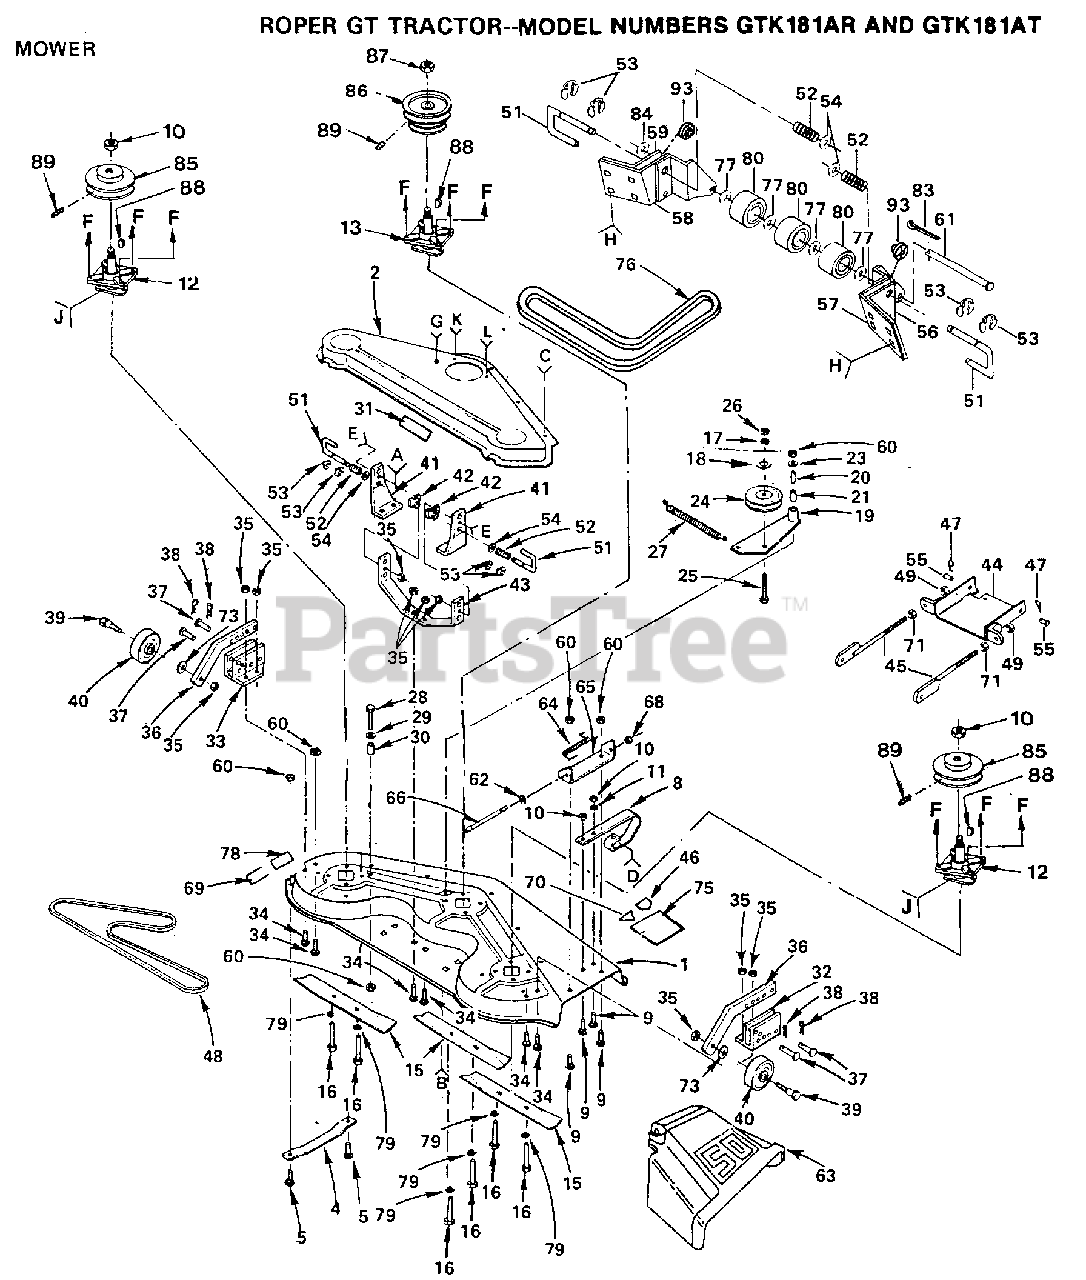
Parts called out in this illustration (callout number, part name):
2	COVER DECK T
4	RUNNER-LH M
5	BOLT
9	BOLT
11	WASHER
16	BOLT.7/16-14X3/4
17	LOCKWASHER
18	WASHER
19	ARM ASSY GT
23	WASHER
24	IDLER-FLAT T
26	NUT.HEX.3/8-16UNC
27	SPRING T
28	BOLT
29	WASHER M
30	SPACER SPLIT LT
32	GUAGE WHL BRKT GT
33	GUAGE WHL BRKT GT
34	BOLT
36	GUAGE WHL BAR GT
39	BOLT M
40	WHEEL.GAGE.BLK.PL
41	SUSP BRKT GT
42	SPACER GT
43	SUSP BRACE GT
45	BRACKET.SUSPEN.AS
46	DECAL HYT
47	RETAINER.SPRING
48	V-BELT M
49	NUT LTV
51	RELEASE PIN GT
52	SPRING M
53	KLIP RING
55	CLEVIS PIN GT
56	BRACKET T
57	BRACKET T
58	BRACKET T
59	BRACKET T
61	PIVOT PIN T
62	WASHER
63	DEFLECTOR
66	ROD-HINGE T
68	NUT PUSH M
69	DECAL INSTRUCTION CAUTION
71	NUT
73	WASHER
77	WASHER T
78	DECAL-INST YT
79	LOCKWASHER
80	ROLLER T
83	COTTER PIN
89	SCR - HEX FGD SOCKET 3/8 X 16 X 1/2
93	SPACER T
